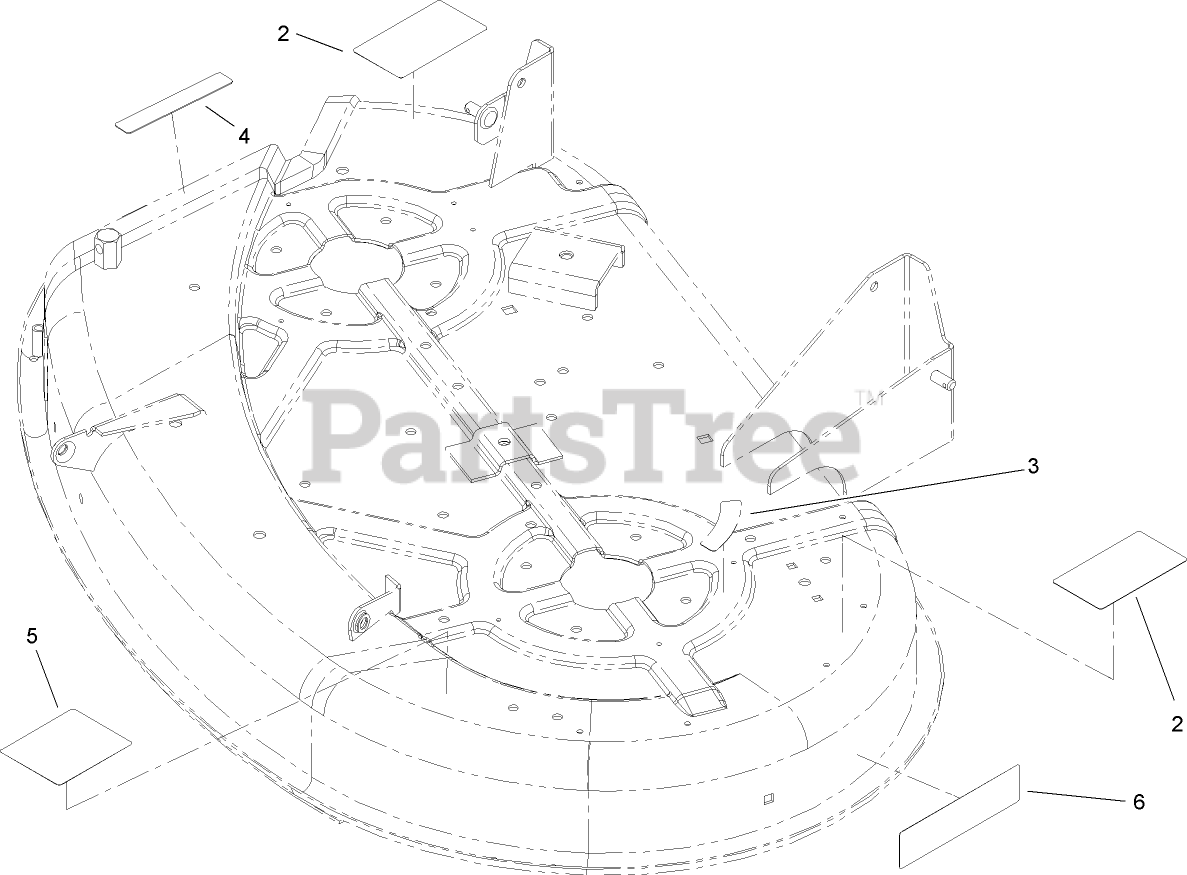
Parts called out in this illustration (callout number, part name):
2	DECAL-DANGER
3	DECAL-DANGER, SHIELD
4	DECAL-DANGER
5	DECAL-ROUTING, BELT
